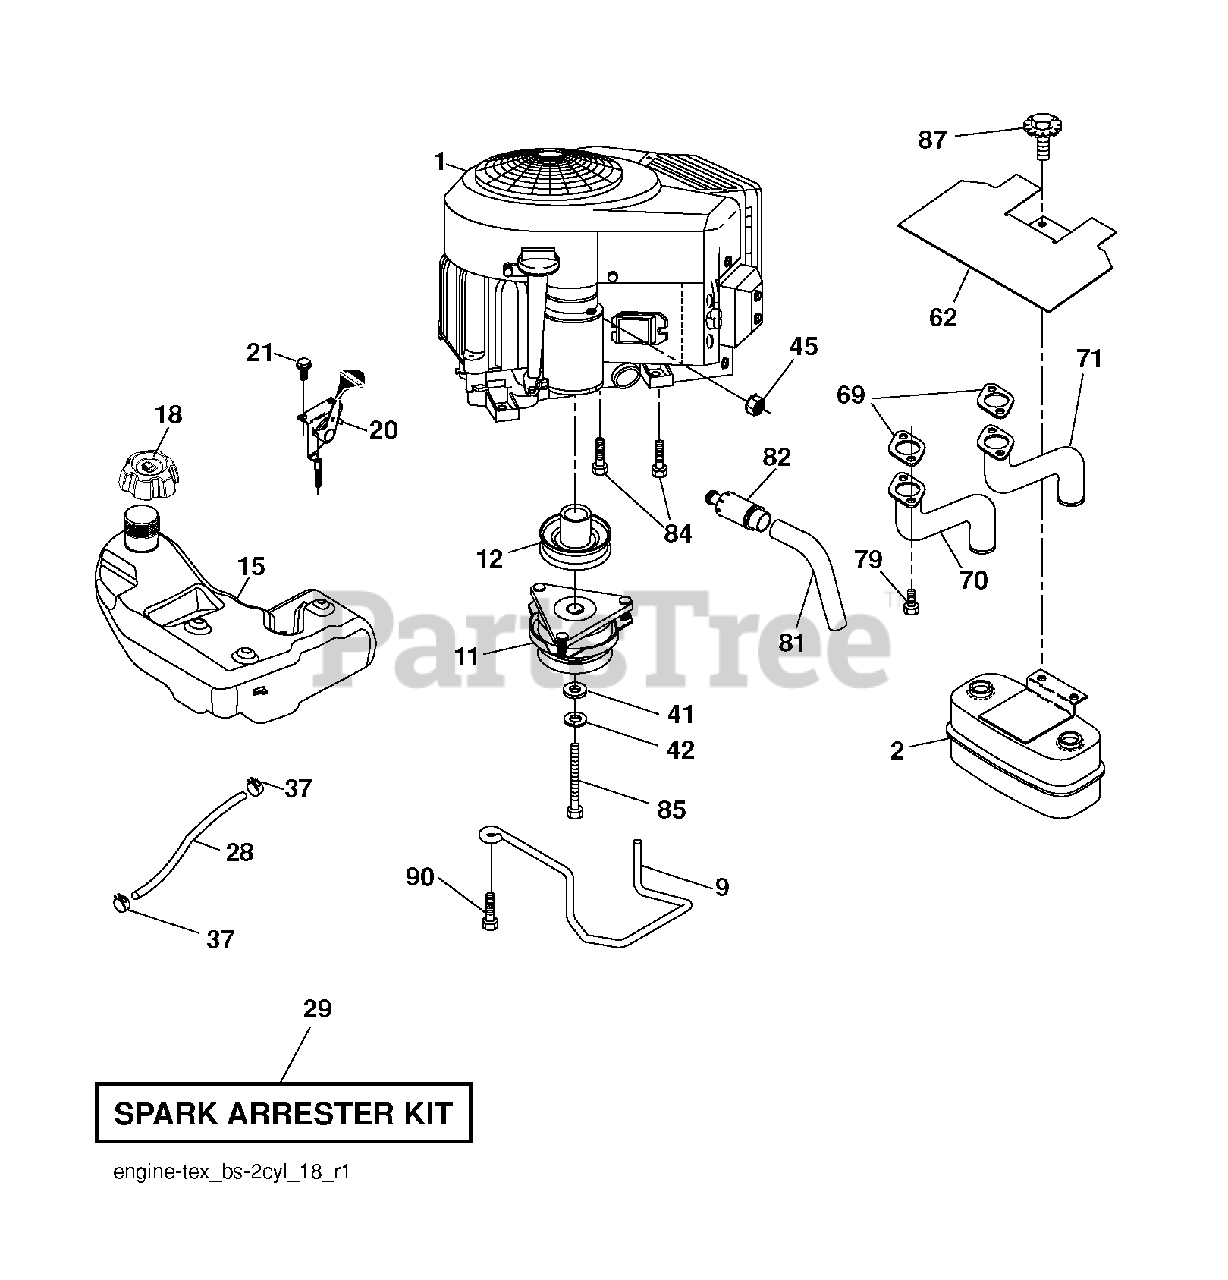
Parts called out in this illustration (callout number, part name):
2	MUFFLER.TWIN.CYL.LOW.TONE
9	KEEPER.BELT.ENGINE.4.2
11	CLUTCH
12	PULLEY.ENGINE.TUFFTORQ
15	TANK.FUEL.4GAL
18	CAP.ASM.FUEL.TANK.3"BL
20	CONTROL.TH/CK.COBRA.B&S.TWN.
21	SCREW.#10 X 0.750.BOS THREAD
28	LINE.FUEL.20
29	ARRESTER SPARK (OPTIONAL)
37	HOSE CLAMP
42	LOCKWASHER
45	NUT
62	RP SHIELD HEAT MUFFLER
69	GASKET.MUFFLER
70	TUBE MANIFOLD LH
71	EXHAUST TUBE RH
79	SCREW.SOCKET.HEAD.5/16-18
81	TUBE, DRAIN OIL ASM.
82	PLUG DRAIN OIL EASY
83	BOLT, 5/16-18 X 1 3/4
84	SCREW.3/8-16
85	BOLT HEX 7/16-20X4-1/4"
90	SCREW 3/8-16X1
